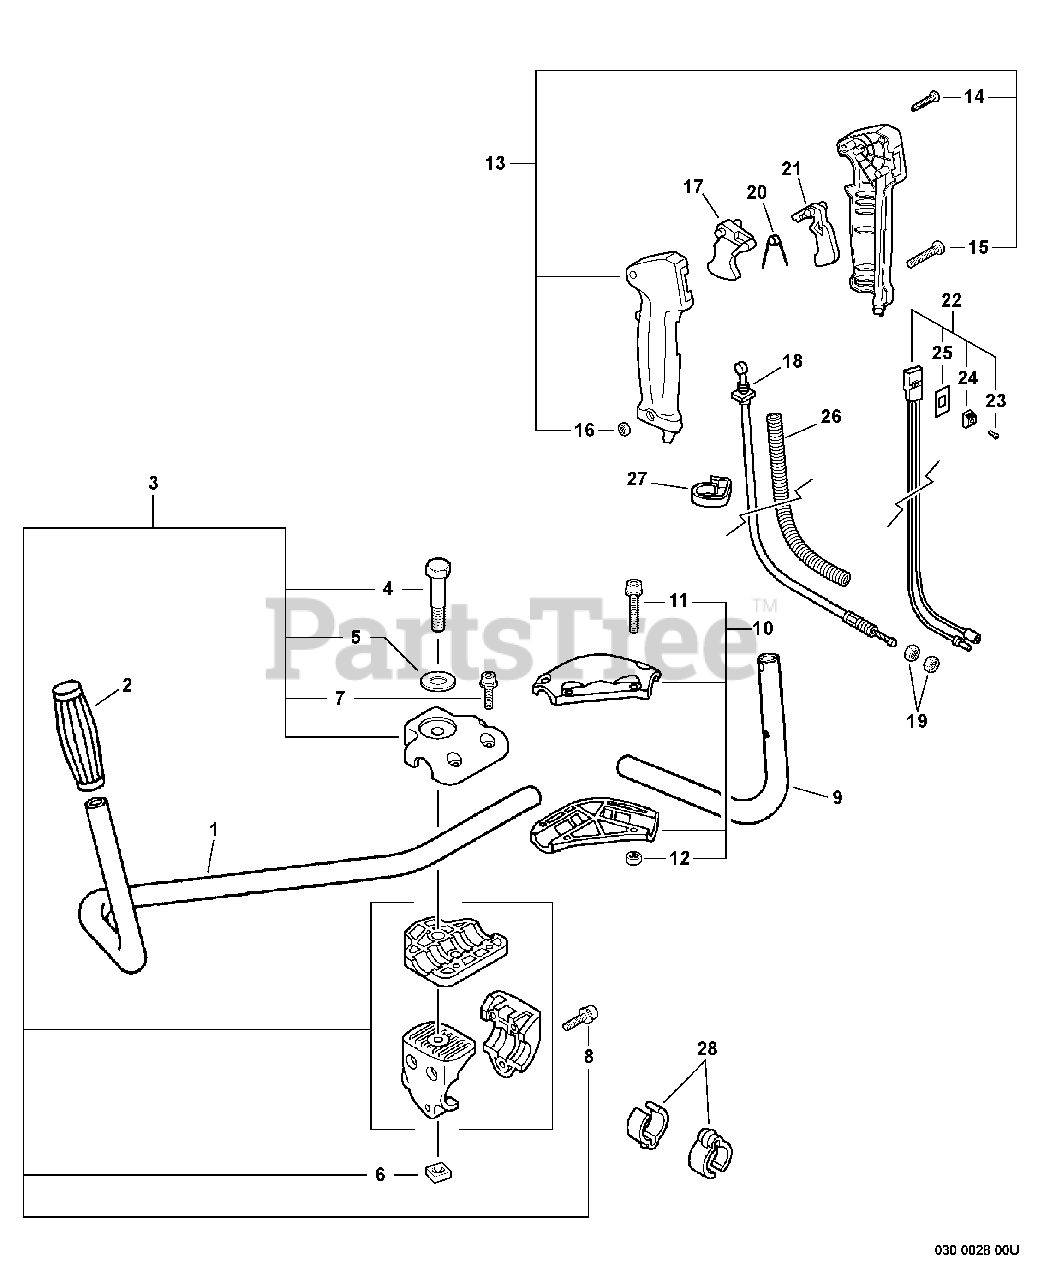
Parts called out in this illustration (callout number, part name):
1	HANDLEBAR, LEFT
2	GRIP, HANDLE
3	HANDLE BRACKET KIT
4	BOLT 8×55
5	WASHER 8
6	NUT 8×1.25
7	BOLT 5×20
8	BOLT 5×30
9	HANDLEBAR, RIGHT
10	BRACKET ASSY, HANDLE
11	BOLT 5×20
12	NUT M5
13	CONTROL HANDLE KIT
14	SCREW 3×25
15	SCREW 5×30
16	NUT M5
17	TRIGGER, THROTTLE
18	CABLE, THROTTLE
20	SPRING, TORSION
21	LOCKOUT, THROTTLE
22	SWITCH, ON-OFF
23	SCREW 3×10
24	KNOB, SWITCH - ORANGE
25	LABEL, SWITCH
26	TUBE, FLEXIBLE 7×820
28	CLIP 28 MM
